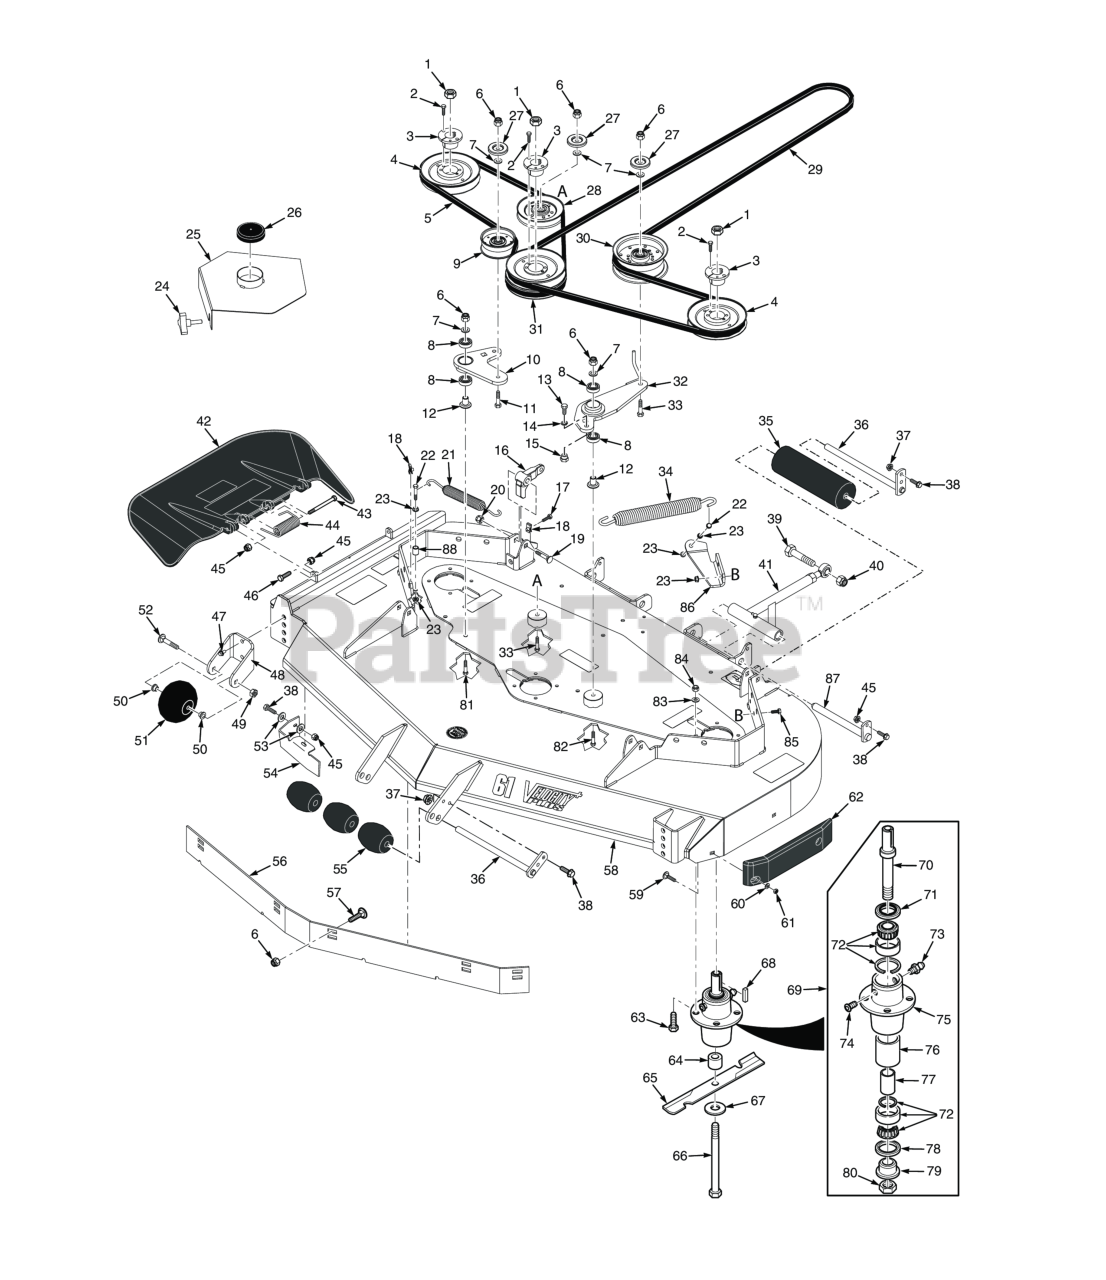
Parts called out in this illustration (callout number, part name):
1	Hex Locknut, Elastic Stop, 3/8-16
2	Bolt, Hex Head 1/4-20 x 1" Grade 8 Black
3	Hub, Tapered 1-1/8" Bore
4	Pulley, Tapered Bore 6.33" Dia.
5	Belt, Deck Drive R.H.
6	HEX NUT, ELASTIC STOP LOCK, 3/8-16
7	Flatwasher, 3/8 (.391 x .938 x .105 HD) Grade 8
8	BEARINGS, BALL, NEUTRAL RETURN
9	Pulley, 3-1/2" Dia.
10	Idler Arm
11	Capscrew, Hex Head 3/8-16 x 2-1/2"
12	Pivot, Idler Short
13	Bolt, Hex Head 7/16-14 x 1"
14	Lockwasher, 7/16� Spring
15	Boss, Spring Anchor - LH
16	Lever, Deck Level
17	Bolt, Hex Head 3/8-16 x 2" Special Lock
18	U-Nut, 3/8-16 (short)
19	Bolt, Carriage 7/16-14 x 2-1/4"
20	HEX LOCKNUT, ELASTIC STOP, 7/16-14
21	Spring, RH Deck Drive
22	Bolt, Hex Head 3/8-16 x 1-1/2" Grade 8 Black
23	NUT, 3/8-16 SERRATED FLANGE HEX HEAD
24	Knob, w/stud 3/8-16 x 1-1/4"
25	Belt Cover Weldment
27	Quick Pin, 5/16" Dia.
28	IDLER PULLEY, "V" GROOVE
29	BELT, DECK DRIVE - SMTC-61V
30	Pulley, Idler 5" Dia.
31	Pulley, Double Groove 6.33" Dia.
32	Idler Arm
33	Bolt, Hex Head 3/8-16 x 3" - 52"
34	Spring, L.H. Deck Drive
35	Wheel, Anti-ScalpRelief Fitting, Tapered Spindle
36	Shaft Weldment, Guide Roller
37	Nut, Flange Head Elastic Stop 5/16-18
38	Bolt, Heax Head 5/16-18 x 1" (48V / 52V)
39	BOLT, HEX HEAD 5/8-11 X 4-1/2"
40	HEX LOCKNUT, ELASTIC STOP, 5/8-11
41	Push Arm (Includes 64,60,62)
42	Discharge Chute Advantage - Large
43	Bolt, 5/16-18 x 4-3/4" Hex Head
44	Spring, Discharge Chute
45	HEX NUT, ELASTIC STOP LOCK, 5/16-18
46	Bolt, Hex Head 5/16-18 x 1-1/2" - Front
47	Capscrew, 3/8-16 x 1.0" Serrated Flange Hex Hd
48	Bracket, Anti-Scalp Wheel
49	Bolt, Hex Head 3/8-16 x 1" Ser. Flg.
50	Bushing, .376" I.D. Oilite
51	Bolt, Carriage 3/8-16 x 4"
52	Bolt, Hex Head 3/8-16 x 3-1/2"
53	Flatwasher, 5/16-.375 x .875 x .083 (35BV & 37BV-EFI)
54	Turbo Baffle, Bolt On
55	Wheel, Anti-Scalp
56	Baffle Custom-Cut, 61V (7-Position)
57	Carriage Bolt, 3/8-16 x 1.0"
58	Cutter Deck Velocity Plus
59	Bolt, 5/16-18 x .75 RHSN Carriage
60	Flatwasher, 5/16-.344 x .688 x .065 (48V / 52V)
61	Nut, Center Lock, 5/16-18(32)
62	Pad, Deck Wear
63	Bolt, Hex Head 5/16-18 x 1-3/4" Grade 8
64	Spacer, Spindle Bottom
65	Cutter Blade, 21" Standard
66	BOLT, HEX HEAD, 5/8-11 X 9-1/2 GR.5
67	Flatwasher, 5/8-.688 x 1-3/4 x .134 HD
68	Key, 1/4 x 1/4 x 2.0"
69	Cutter Spindle Assembly
70	Spindle Shaft, Tapered Brng
71	SEAL, 2.00 O.D. X 1.50 BORE
72	Tapered Bearing Set (Two Bearings W/Race)
73	GREASE FITTING, STR. 1/4-28 SELF TAP.
74	RELIEF FITTING, TAPERED BEARING SPINDLE
75	Housing, Spindle
76	Spacer, Outside, Cutter Spindle
77	SLEEVE, CUTTER SPINDLE
78	Seal, 2.00" O.D. x 1.625" Bore
79	SPINDLE BUSHING, BOTTOM
80	Nut , Spec ial 1 -1/ 1 6 - 1 8
81	Bolt, Hex Head 3/8-16 x 2-1/4" - 61"
82	Capscrew, Hex Head 3/8-16 x 3.25"
83	Lockwasher, 5/16 (.317 x .586 x .078) Helical Spring
84	Lock Nut, 5/16-18 Elastic Stop Grade 8
85	Bolt, Hex Head, 3/8-16 x 1 Gr. 5
86	Bracket, Spring Anchor
87	Shaft Weldment, Pusharm
88	SPACER, IDLER
